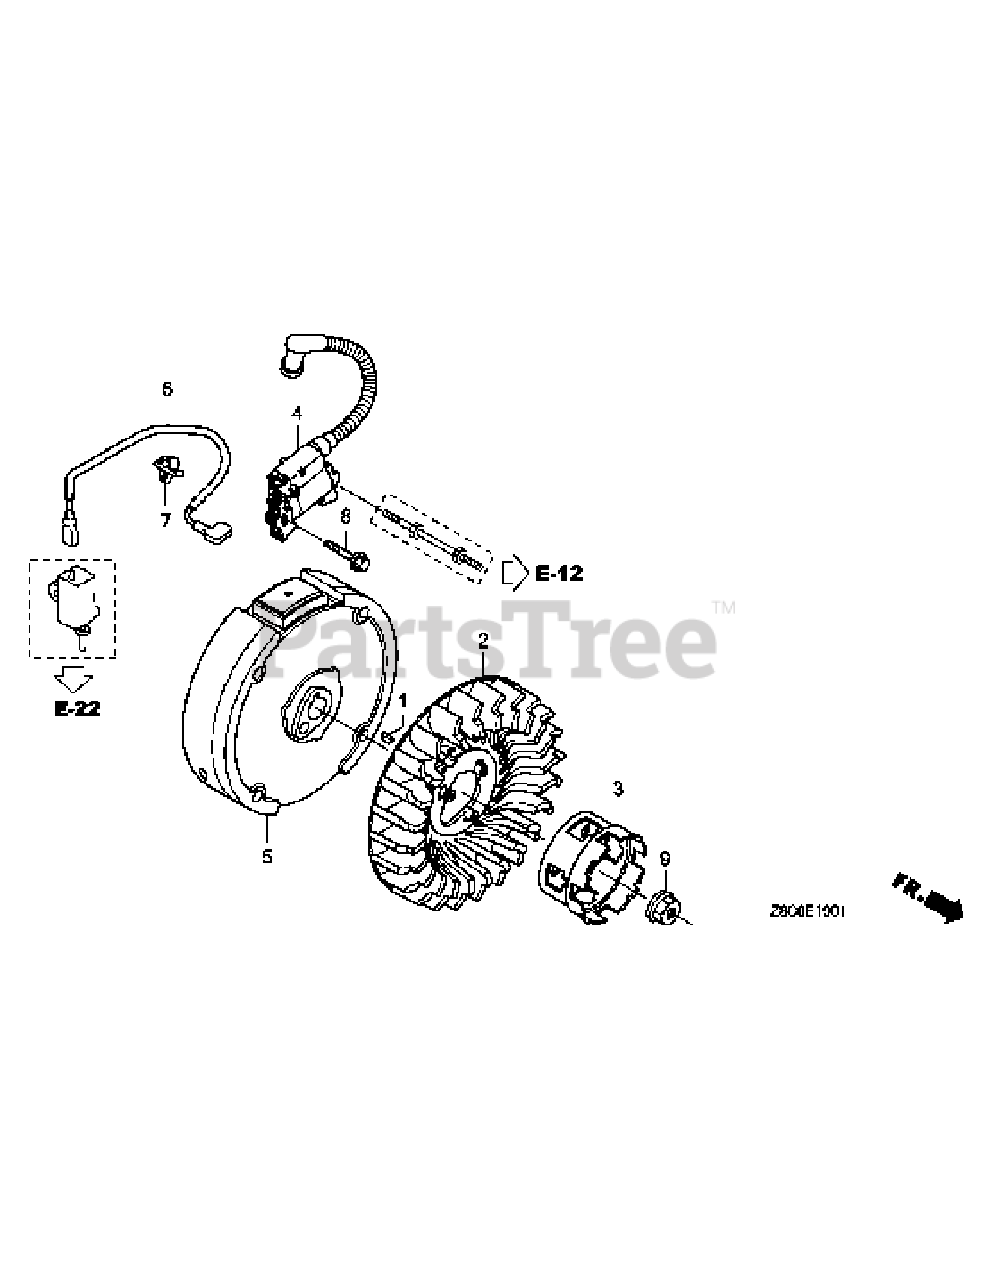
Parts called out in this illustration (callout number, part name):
1	KEY, SPECIAL WOODRUFF (25X18)
2	FAN, COOLING
3	PULLEY, STARTER
4	COIL ASSY., IGNITION (TOYO)
5	FLYWHEEL
6	WIRE, STOP SWITCH
7	HOLDER, STOP SWITCH WIRE
7	HOLDER, WIRE (FASTEX)
8	BOLT, FLANGE (6X23) (CT200)
9	NUT, SPECIAL (14MM)
